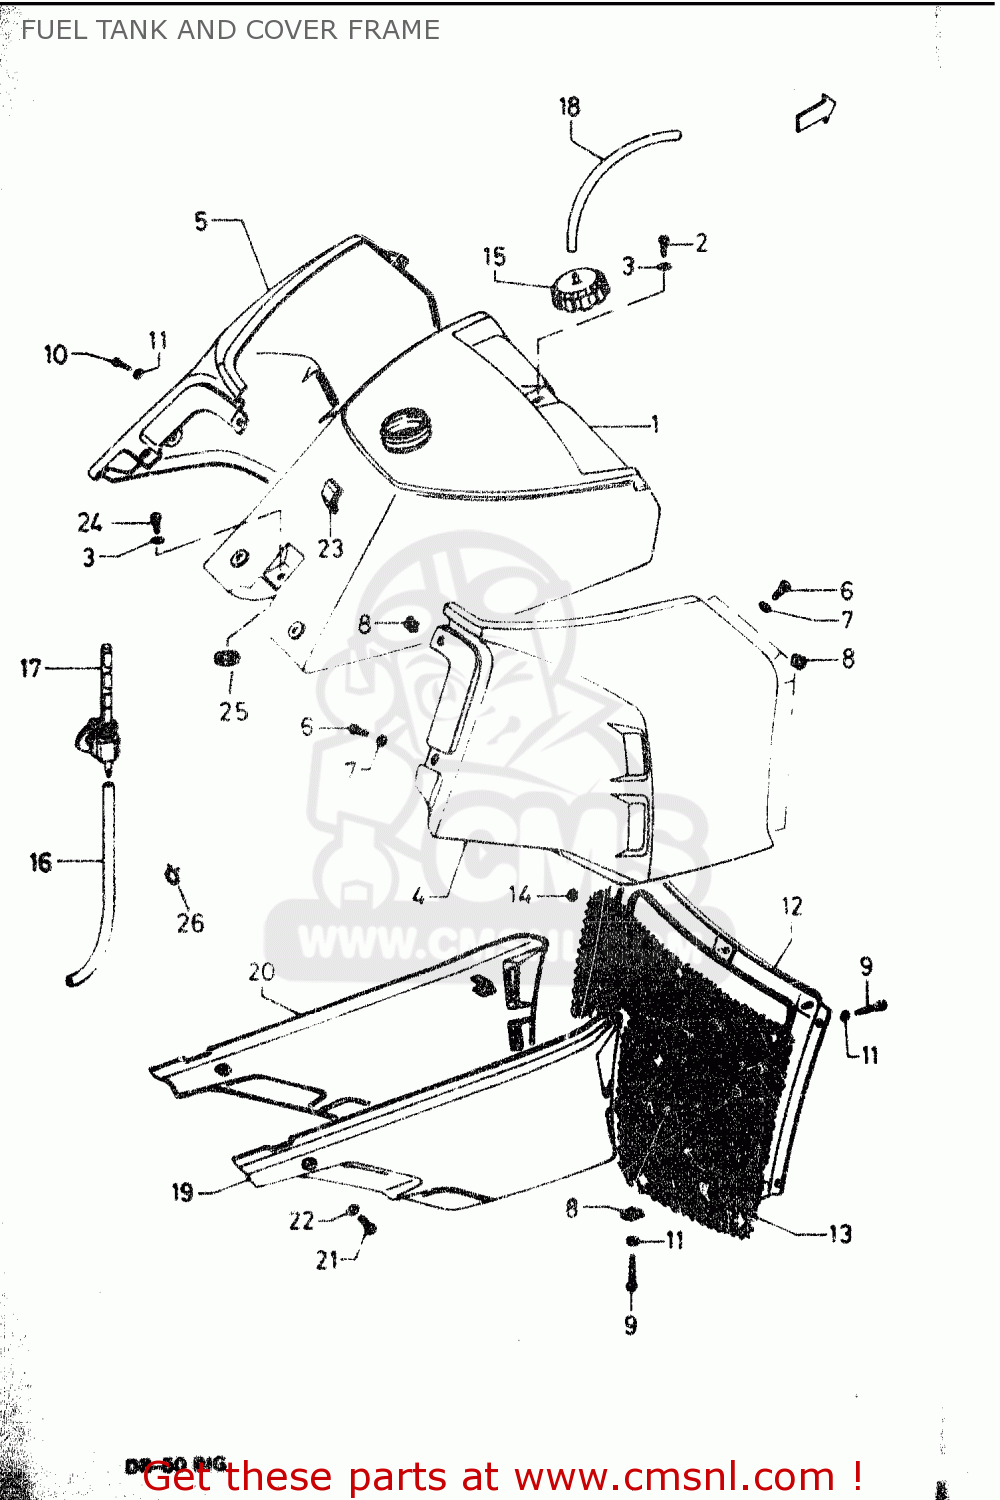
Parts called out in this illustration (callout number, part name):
1	TANK ASSY, FUEL
2	SCREW M6X16 DIN 7985/N
3	WASHER B6 DIN 9021/N
4	COVER, FUEL TANK RH (BLUE)
5	COVER, FUEL TANK RL (BLUE)
6	SCREW M5X10 DIN 7985/N
7	WASHER 5 DIN 9021
8	NUT (NUL 522-4A)
9	SCREW 3.9X13 DIN 7981
10	TAPPING SCREW 4X10/A
11	WASHER B4 DIN 125
12	BUMPER, COOLER
13	WIRE MESH
14	NUT 4X15 ST
15	CAP, FUELTANK
16	HOSE 4.5X75X125
17	COCK ASSY, FUEL
18	HOSE, (L:260)
19	COVER, FRAME RH (BLUE)
20	COVER, FRAME LH (BLUE)
21	SCREW M6X10 DIN 7985/N
22	WASHER B6 DIN 125
23	GASKET
24	SCREW M5X25 DIN 7985/N
25	CUSHION
26	CLIP
